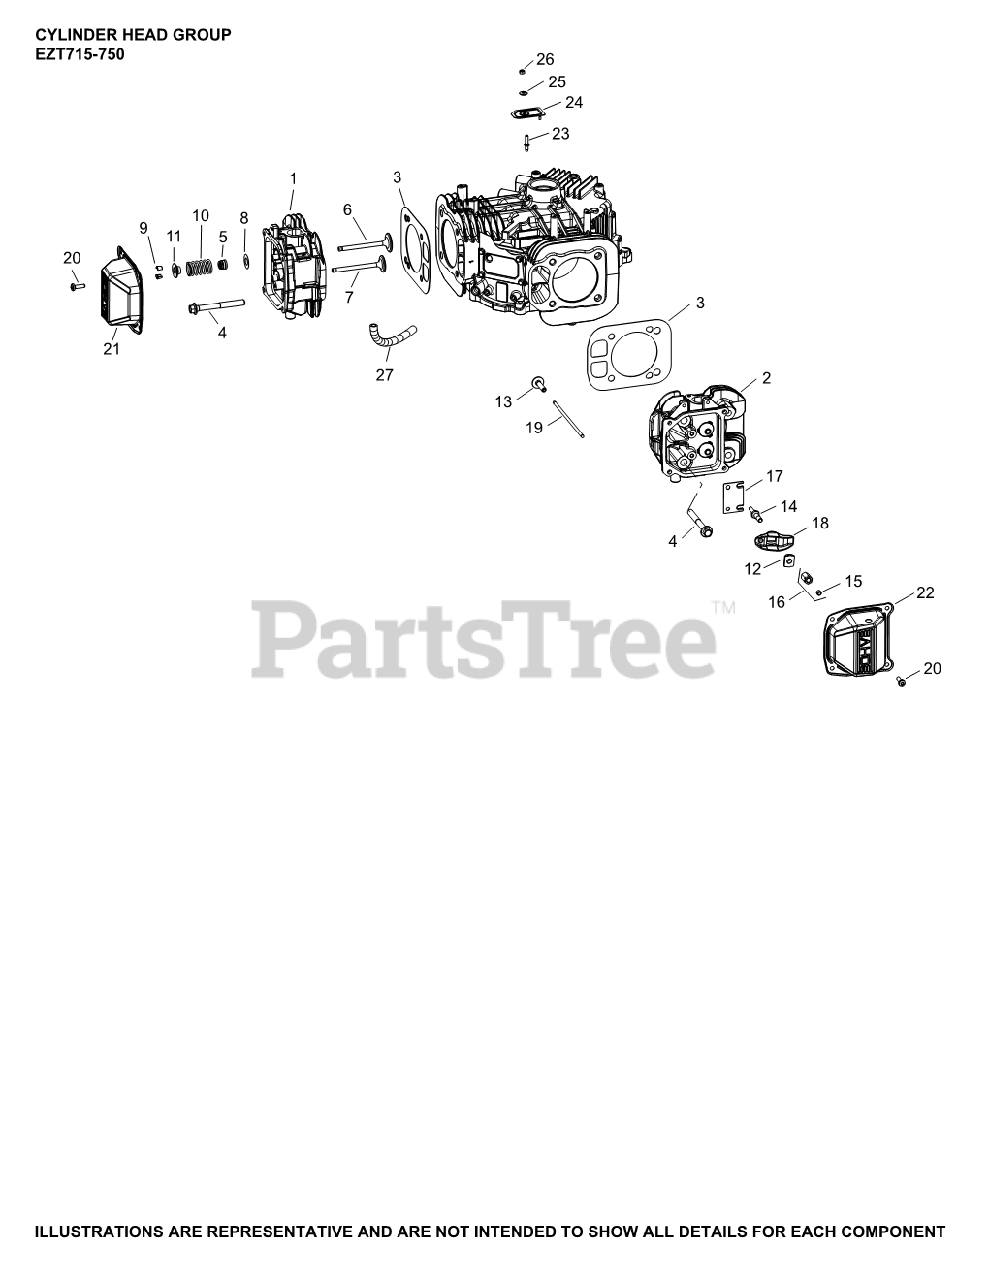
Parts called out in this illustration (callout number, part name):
1	CYLINDER HEAD (#1)
2	CYLINDER HEAD (#2)
3	KIT, CYLINDER HEAD GASKET
4	SCREW, FLG M10X1.5X90
5	SEAL, VALVE BAND
6	VALVE, INTAKE
6	VALVE, INTAKE (.25)
7	VALVE, EXHAUST
7	VALVE, EXHAUST (.25)
8	SPACER (.010")
9	KIT, RETAINER
10	SPRING VALVE
11	CAP, VALVE SPRING
12	PIVOT, ROCKER ARM
14	STUD, ROCKER
15	SCREW, SET
16	HEX NUT ASSEMBLY
17	PLATE, GUIDE
18	ARM, ROCKER
19	ROD, PUSH
20	SCREW , PAN HEAD
21	COVER, ROCKER STAMPED STEEL
22	COVER, ROCKER STAMPED STEEL
24	COVER, BREATHER REED
25	WASHER, SEALING
26	NUT, LOCK M5X.8
27	HOSE, BREATHER
